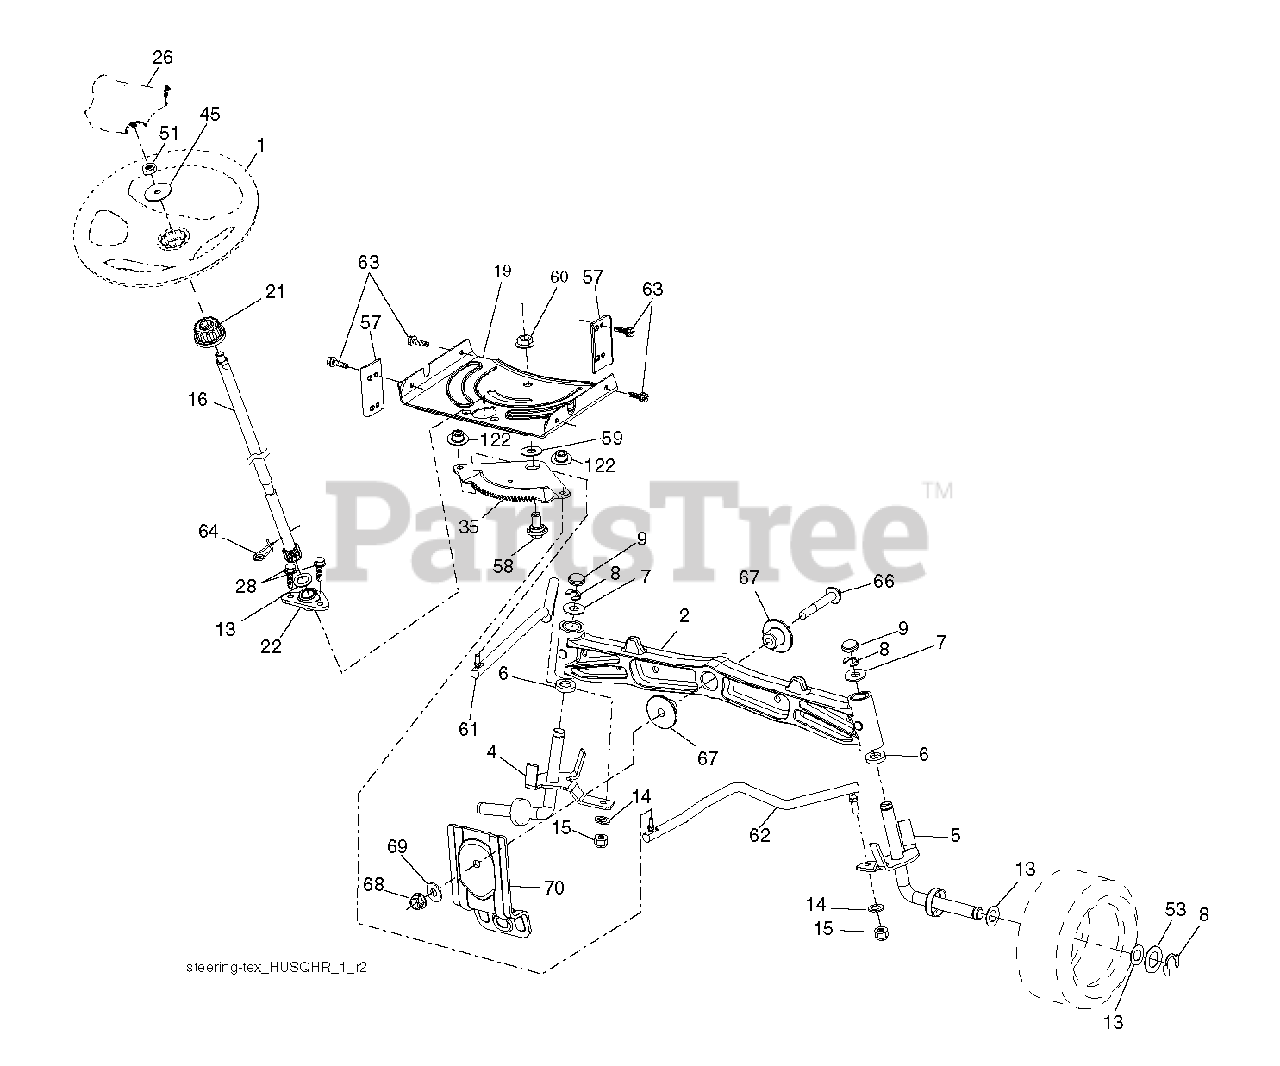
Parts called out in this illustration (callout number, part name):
1	WHEEL.STEER.HUSQ.SR.498.OVMLD
2	AXLE.CAST.IRON
4	SPINDLE.WELDED.LH.15"TEX
5	SPINDLE.WELDED.RH.15"T
6	THRUST WASHER
9	CAP.SPINDLE.BLACK
14	WASHER, LOCK 3/8
15	NUT CROWNLOCK 3/8-24
16	SHAFT, STEERING
19	PLATE.STEER.DDL.NLT/NG
21	ADAPTER, WHEEL STNG..
22	STEERING.SUPT.LOWER.
26	INSERT.CAP.WHL.STRG.HUSQ.PREM
28	SCREW, 3/8-16X3/4
35	GEAR.SECTOR.PLATE.DDL.
45	WASHER 9/16"ID, 2 3/8"OD
51	NUT.HEX.1/2-20
53	WASHER.HARDENED
57	BRACKET.UPSTOP.TEX
58	BOLT.SHOULDER.SECTOR.P
59	WASHER.THURST.SECTOR.S
60	NUT FLANGE LOCK 5/8-11
61	DRAGLINK.LH.BALLSTUD.D
62	DRAGLINK.RH.BALLSTUD.D
63	SCREW
64	RETAINER.CLIP.SPRING.S
66	BOLT HEX FGHD 7/16-14 X 3 SERR
67	BUSHING.PM.FRONT AXLE
68	NUT.LOCK.FLANGE.7/16
69	WASHER.1.5X.505X.118
70	BRKT.DECK.SUSPENSION.F
122	CAP.GEAR.SECTOR.TEX
